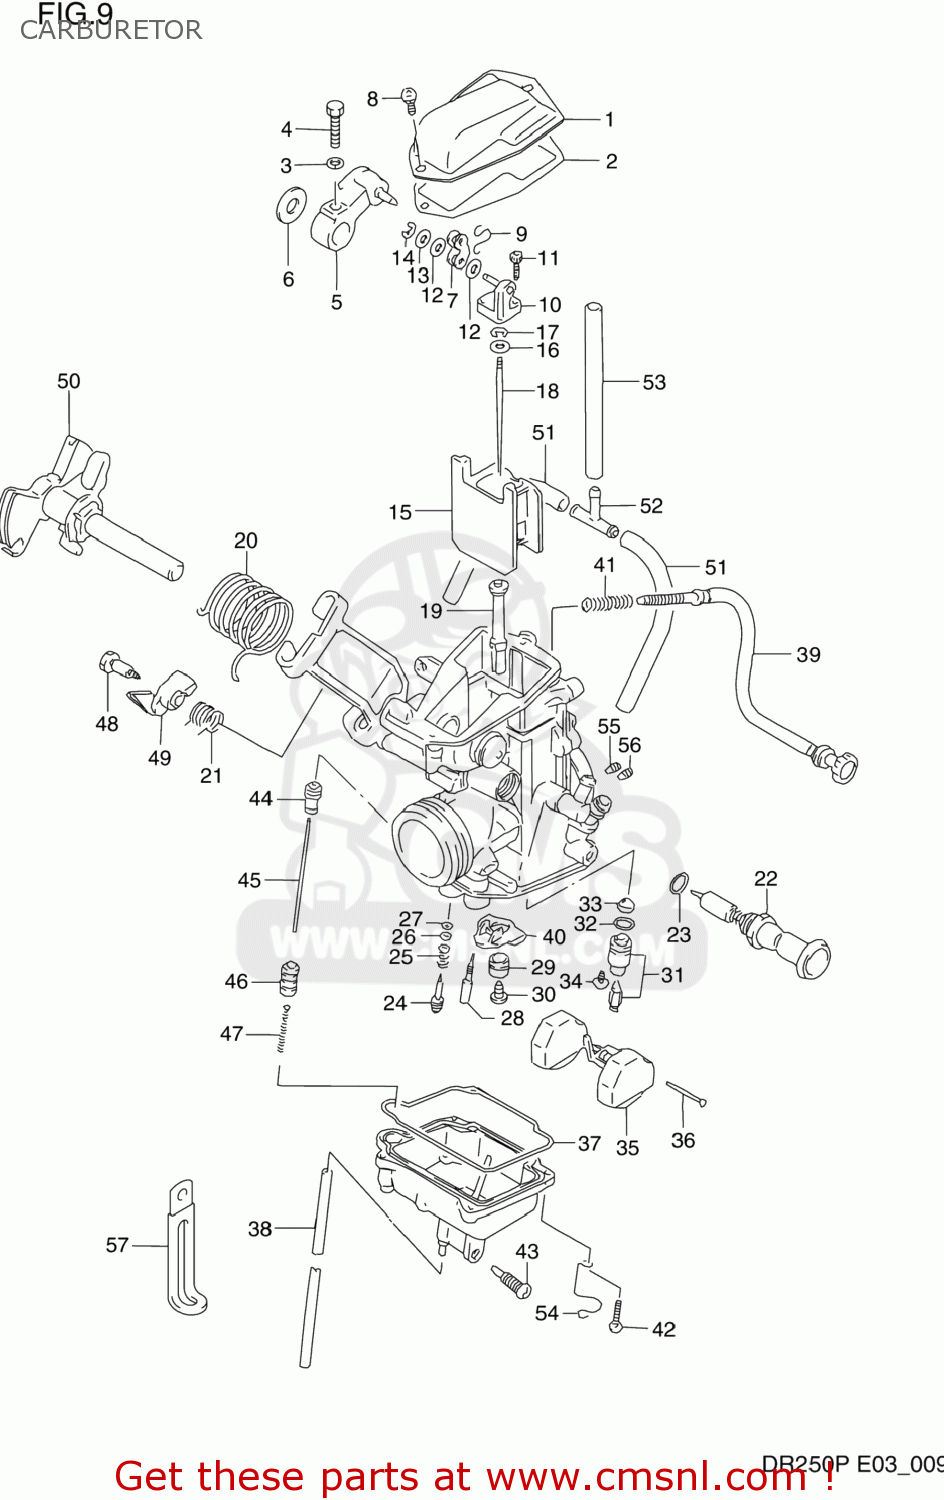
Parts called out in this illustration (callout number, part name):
1	COVER,CARBURETOR,TOP
2	GASKET,CARBURETOR TOP (NAS)
3	WASHER
4	BOLT
5	ARM,THROTTLE
6	RING,THROTTLE SHAFT
7	PLATE
8	SCREW
9	SPRING
10	CONNECTOR
11	SCREW
12	GASKET (NAS)
13	WASHER
14	E-RING
15	VALVE,PISTON
16	WASHER,JET NEEDLE
17	CLIP
18	NEEDLE,JET
19	JET,NEEDLE (P-9)
20	SPRING
21	SPRING
22	PLUNGER ASSY
23	O RING
24	SCREW,PILOT
25	SPRING
26	WASHER
27	O RING,PILOT AIR SCREW
28	JET,PILOT (35)
29	RING,MAIN JET FIXING
30	JET
31	VALVE ASSEMBLY,NEEDLE
32	O-RING,NEEDLE VALVE
33	FILTER
34	SCREW
35	FLOAT
36	PIN,FLOAT
37	O RING,FLOAT CHAMBER
38	HOSE
39	ADJUSTER ASSY
40	RING
41	SPRING
42	SCREW
43	SCREW,DRAIN
44	BOOT, ACCELE PUMP ROD
45	ROD,PLUNGER
46	PLUNGER
47	SPRING
48	BOLT
49	LEVER
50	SHAFT ASSEMBLY
51	HOSE
52	JOINT,3 WAY
53	HOSE
54	CLIP
55	JET,AIR(0.6)
56	JET,AIR(1.3)
57	CLAMP L:35
